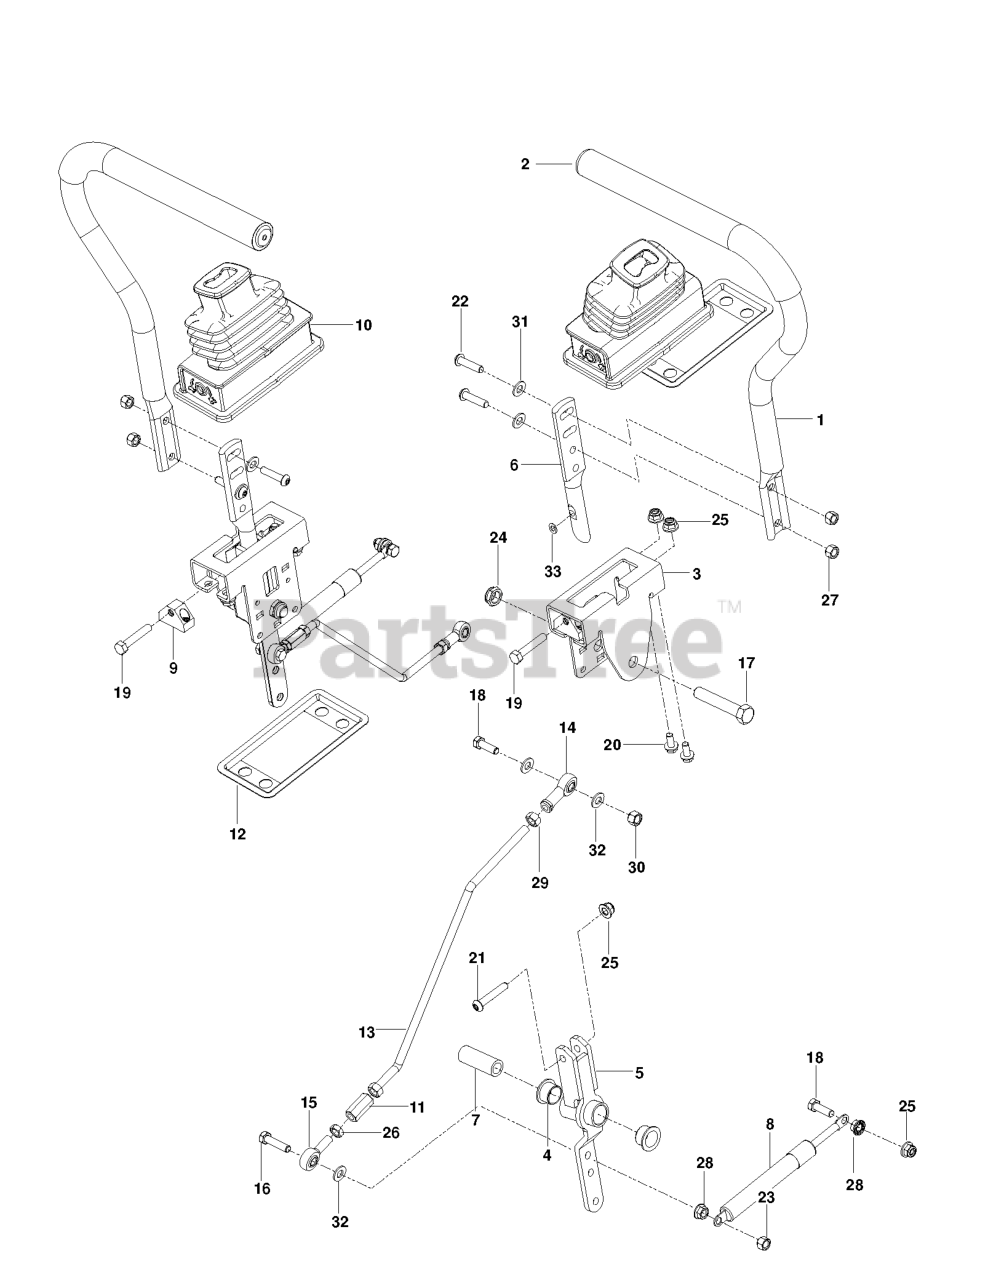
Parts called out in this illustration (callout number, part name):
1	CONTROL.TUBE.RZ (2 2)
2	GRIP, DRIVE LEVER
3	BRACKET.CONTROLS.ZTR.X431
4	BEARING, FLANGE
5	LEVER CONTROL PIVOT
6	CONTROL.LEVER.HANDLE
7	SPACER.PIVOT.CONTROL
9	BLOCK TRACKING CONTROL ZTR
10	BOOT.STEERING.LEVER
11	ROD END COUPLER
12	CONTROL.BOOT.FLANGE.X431
13	ROD MOTION CONTROL
14	RH ROD END
15	RP.ROD.END.LH
17	HCS 1/2-13 X 2-3/4 GD 5 ZD
18	BOLT.FIN.HEX.5/16-18UNC X 1.00
19	SCREW.SHAKEPROOF.1.25.BLACK
20	HHFS 5/16-18 X 3/4
21	SCREW 5/16-18 X 1 3/4 BTN-HD
22	BUTTONHEAD.5/16-18X1.125.BLACK
23	NUT.71038.31-18.HEX.NYLOCK
24	NUT 1/2-13 HEX JM NYL
25	5/16-18 NYLOC FLANGE NUT
26	NUT 5/16F LEFTHAND
27	NYLOCK.NUT.5/16-18 BLACK
28	NUT 5/16C WHIZ
30	5/16-18 THIN PROF NY
31	WASHER.11/32X11/16 BLACK
32	WASHER
33	WASHER.11/32ID.11/16OD.116THIC
